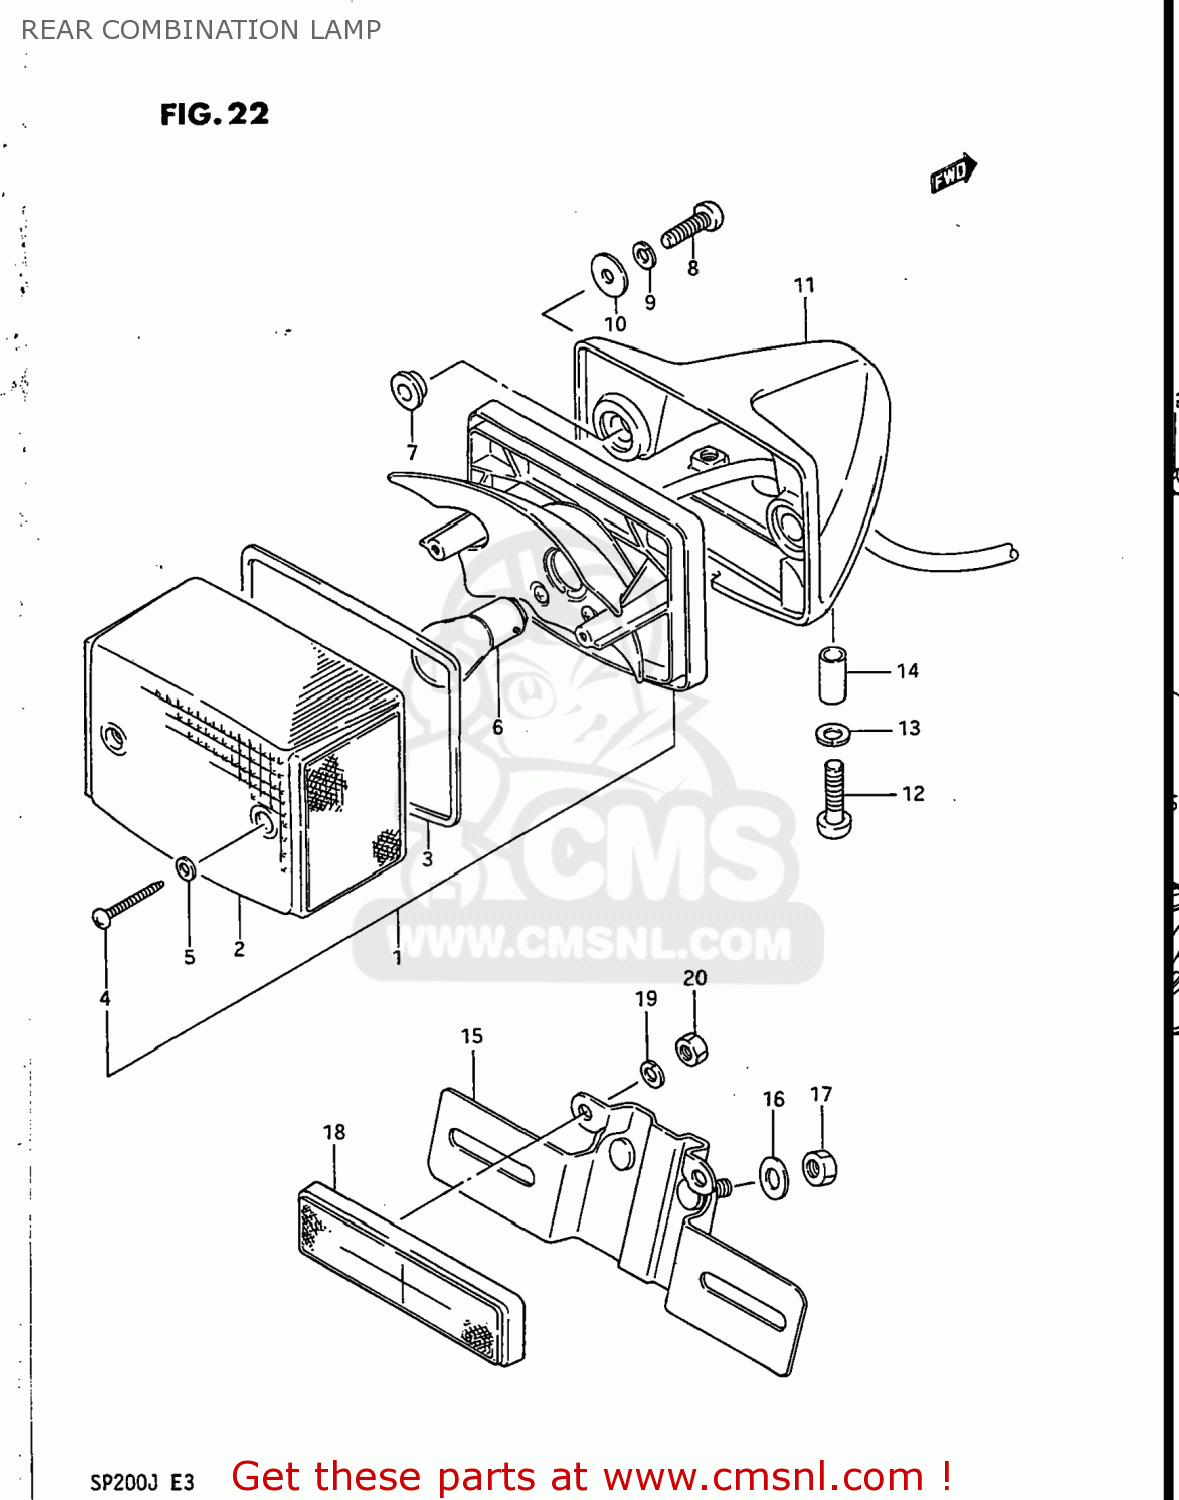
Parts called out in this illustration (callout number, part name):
1	LAMP UNIT,REAR COMBINATION
2	LENS
3	GASKET (NAS)
4	SCREW
5	GASKET (NAS)
6	BULB(12V23/8W,TOKAI DENSO)
7	SPACER,RR COMBI
8	SCREW 5X20
9	WASHER,LOCK
10	WASHER
11	BRACKET UNIT,TAIL LAMP
12	SCREW
13	WASHER,LOCK
14	SPACER(6.4X9.2X12)
15	BRACKET,LICENSE PLATE
16	WASHER (6.5X24X1.6)
17	NUT
18	REFLEX REFLECTOR,RR
19	WASHER,LOCK
20	NUT
